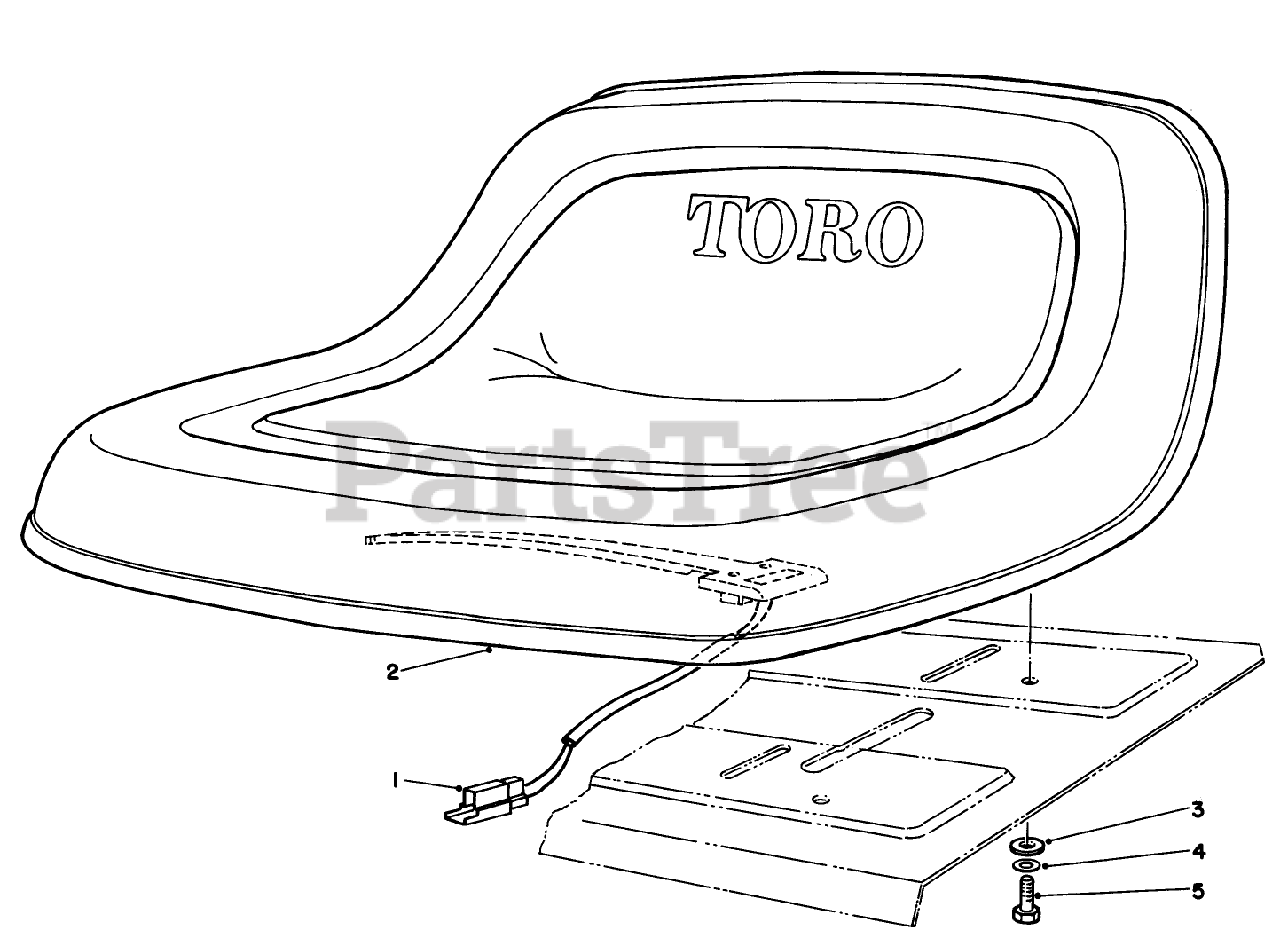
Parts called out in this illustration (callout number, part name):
1	SWITCH-SEAT
2	Seat
3	WASHER-PLAIN
4	WASHER-LOCK
5	SCREW-HH
